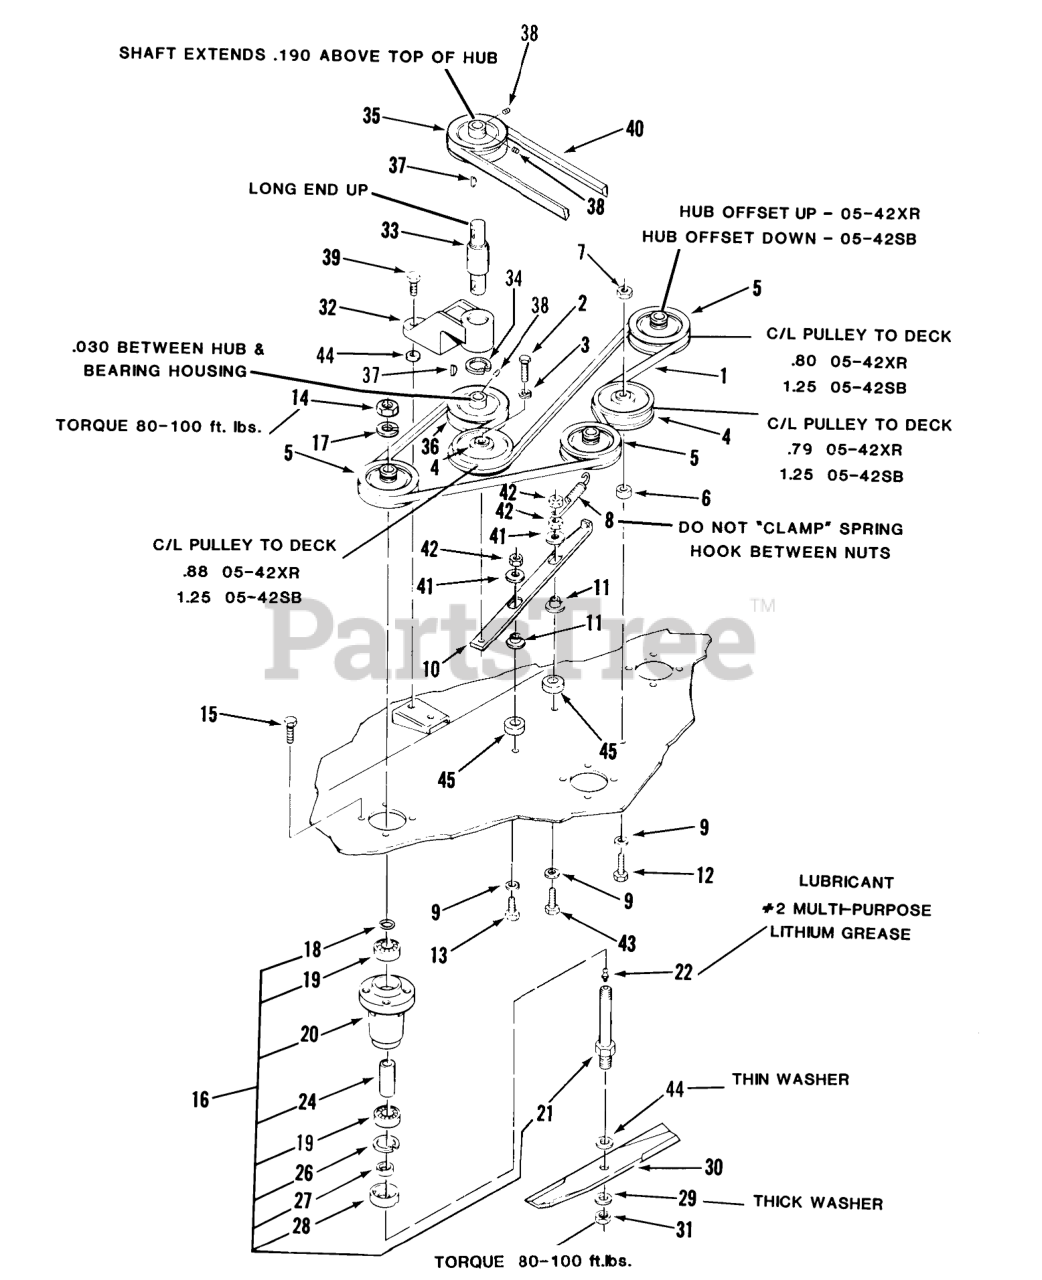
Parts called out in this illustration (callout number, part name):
1	V-BELT
2	BOLT HEX SPECIAL
3	LOCKWASHER
4	Idler Pulley
5	PULLEY
6	SPACER
7	Nut
8	SPRING-EXTENSION
9	WASHER
10	BAR-SLIDER
11	SPACER-BUSHING
12	Bolt
13	Bolt
14	Jam Nut
15	Bolt
16	Spindle Assembly
17	Lockwasher
18	O RING
19	BEARING-BALL
20	HOUSING-SPINDLE
21	Spindle Shaft
22	Zerk
26	Ring-Snap
27	SPACER-BLADE
28	CUP-SPINDLE
29	SpeciaI Washer
30	BLADE KIT
31	Nut-Jam
32	HOUSING DRIVE BRG R
33	BEARING-INT SHAFT
34	Snap Ring
35	PULLEY
36	PULLEY-SPLIT
37	KEY-WOODRUFF
38	Set Screw
39	Bolt
40	V-BELT
41	WASHER
42	NUT
43	Bolt
44	Washer
45	SPACER
